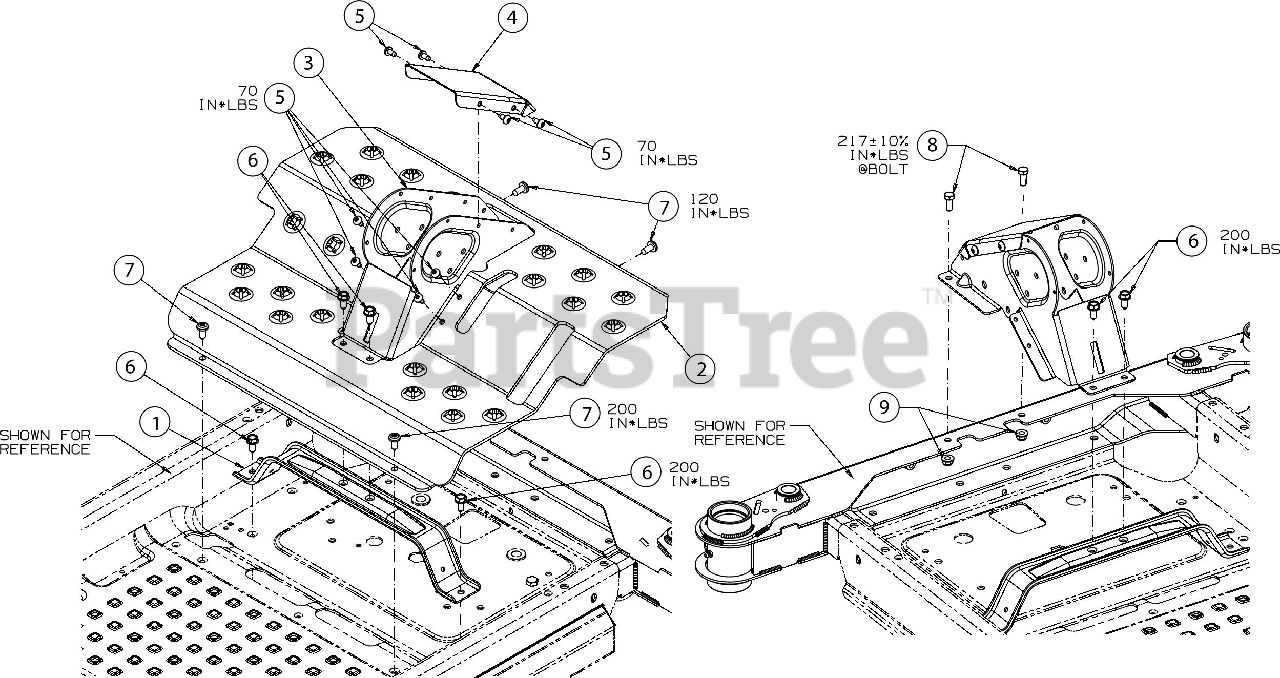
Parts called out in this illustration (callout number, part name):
1	STEERING SUPPORT BRACKET
2	FLOOR BOARD BASE
3	LOWER STEERING COLUMN
4	LOWER COLUMN COVER
5	SCREW 1/4-20 x .500
6	SCREW 5/16-18 x .750
7	SCREW 5/16-18 x .750
8	SCREW 5/16-18 x .75 GR5
9	FLANGE LOCK NUT 5/16-18
